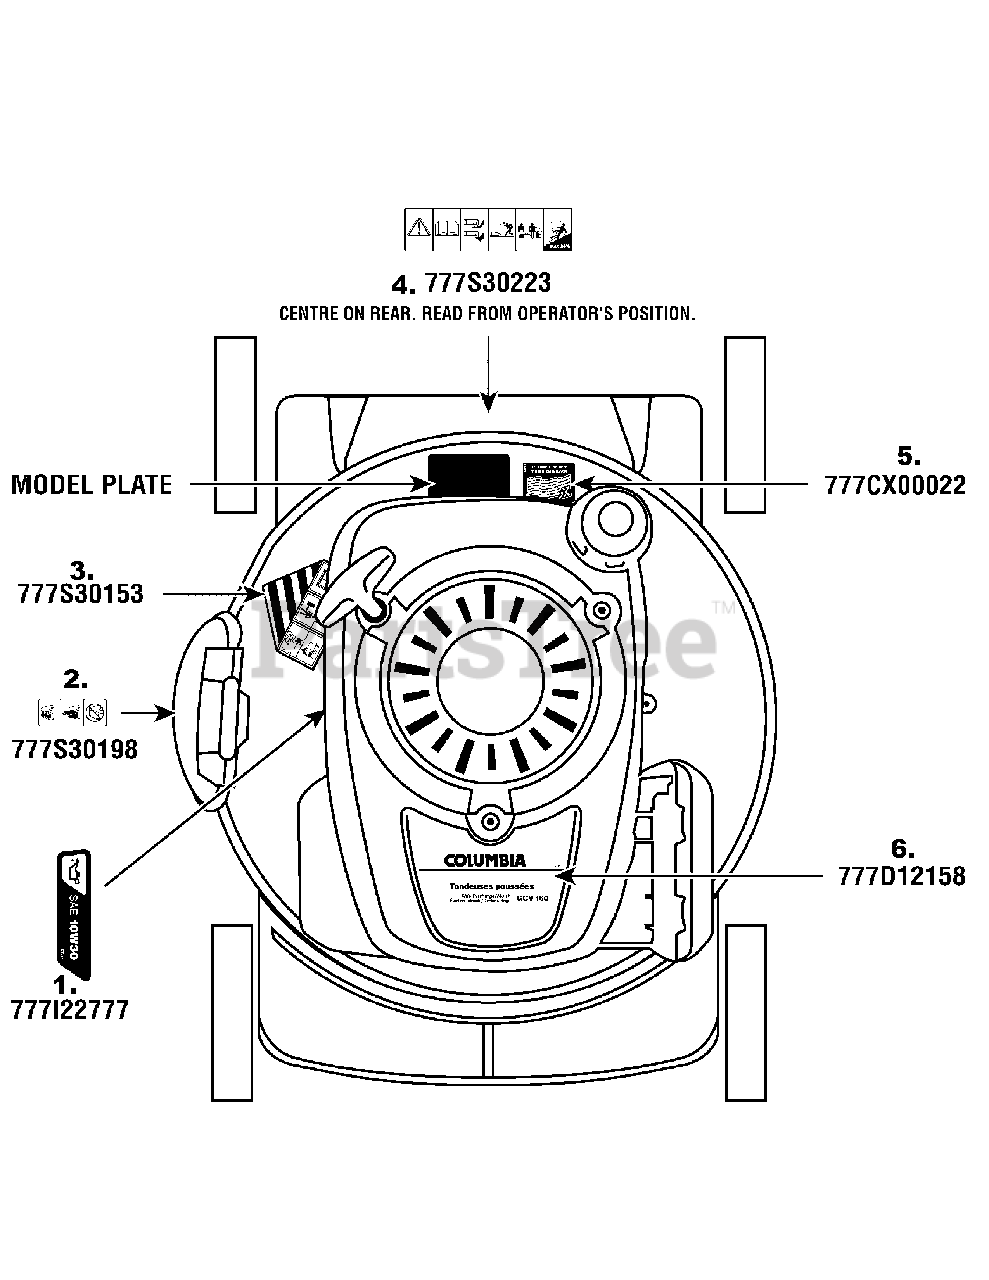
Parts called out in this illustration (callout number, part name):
3	LABEL-DANGER CHUTE
4	LABEL:MOWER DPDM
5	LBLX: MADE IN USA
6	LABEL-ENG SHROUD COLUMBIA
